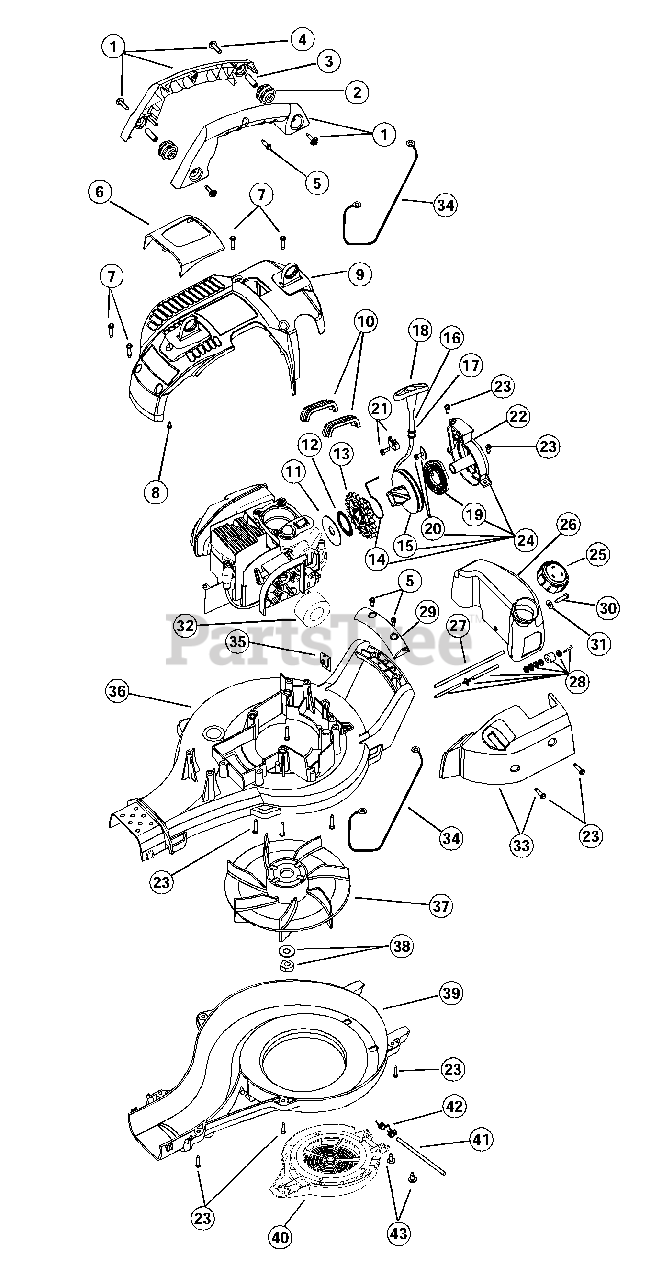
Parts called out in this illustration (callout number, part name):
1	Handle Grip Assembly
2	Vibration Dampner
3	Dampner Spacer
4	Handle Screw
5	Screw
6	Diverter
7	Cover Screw
8	Baffle Screw
9	Engine Cover Assembly
10	Fuel Tank Pad
12	Gear Return Spring
13	Pulley Gear
14	Friction Spring
15	Starter Pulley
17	Rope Guide
18	Pull Handle
19	Rewind Spring
20	Pulley Retainer Assembly
21	Rope Guide Retainer Assembly
22	Recoil Housing
23	Recoil Case Screw
24	Recoil Housing Assembly
25	Fuel Cap
26	Fuel Tank Assembly
27	Fuel Line
28	Fuel Line Assembly
29	Assist Handle
30	Fuel Tank Screw
32	Air Filter Assembly
33	Air Filter Cover
34	Ground Wire
35	Tinnerman Nut
36	Upper Housing Assembly
37	Impeller
38	Washer and Lock Nut Assembly
39	Lower Housing with Insert
40	Vacuum Door Assembly
41	Hinge Shaft
